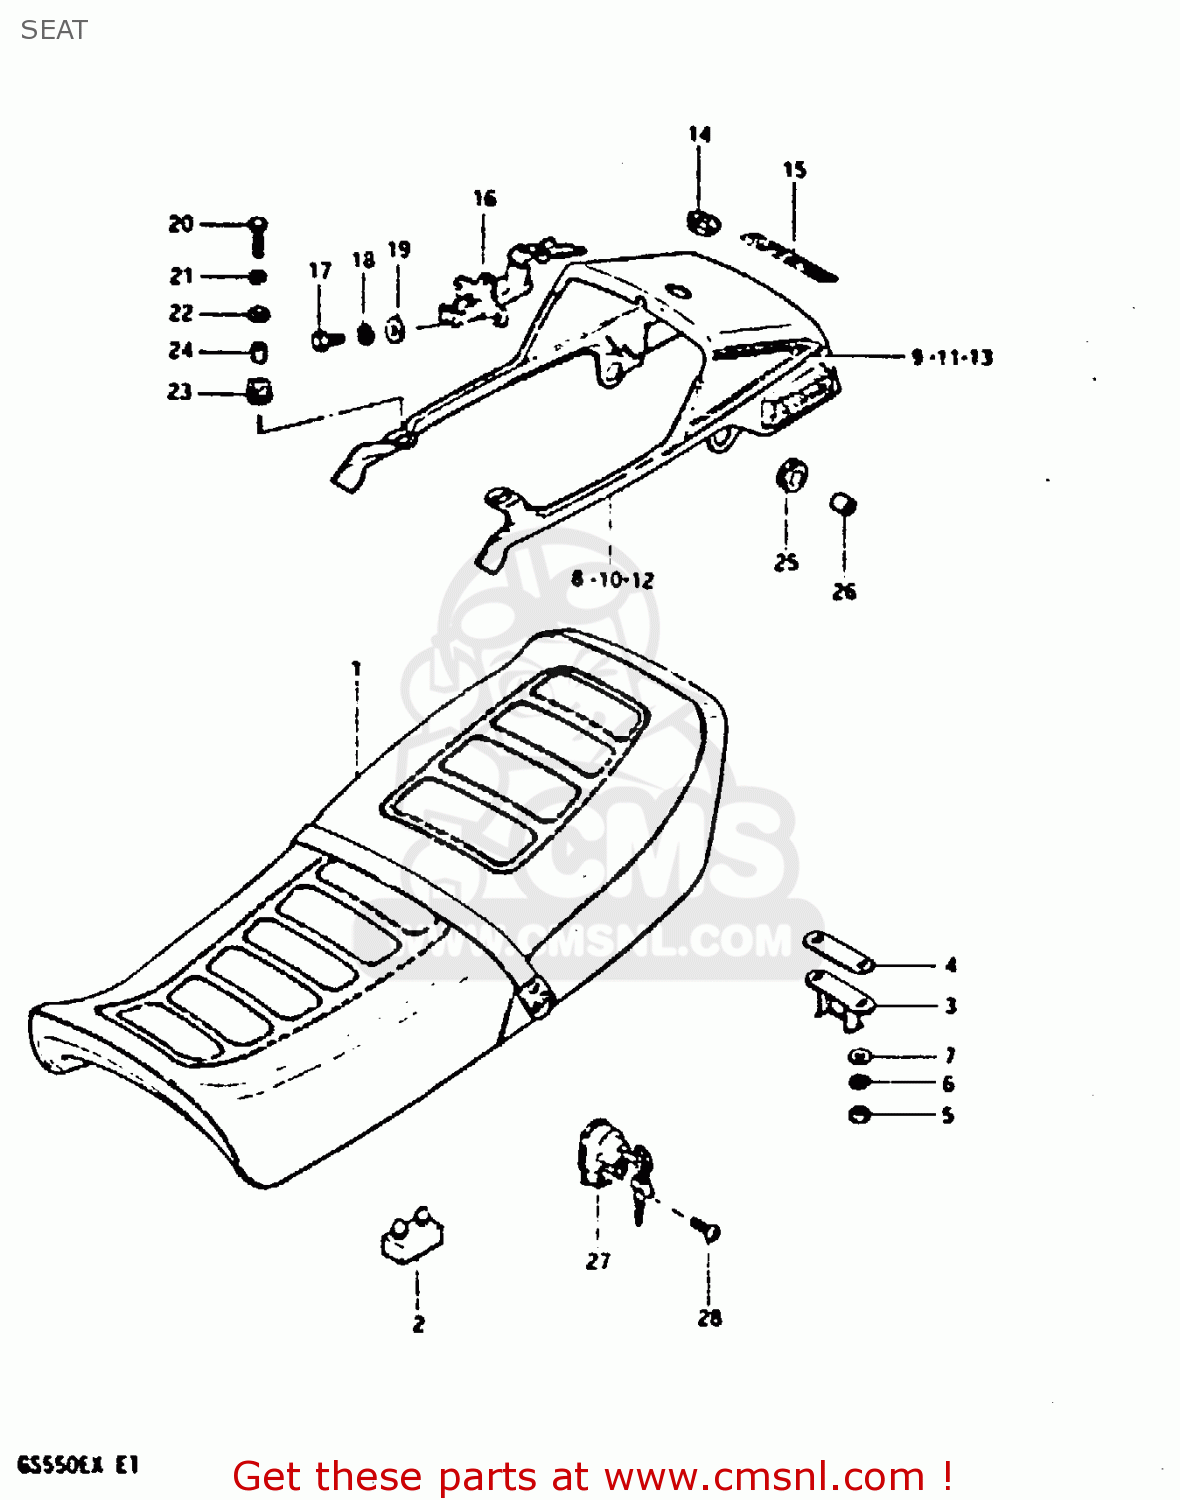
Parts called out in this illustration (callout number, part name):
1	SEAT ASSEMBLY
2	CUSHION
3	STRIKER,SEAT LOCK
4	SHIM,SEAT LOCK STRIKER
5	NUT 6MM
6	LOCK WASHER
7	WASHER
8	COVER, SEAT TAIL (BLACK)
9	TAPE SET
10	COVER, SEAT TAIL (RED)
11	TAPE SET
12	COVER, SEAT TAIL (BLUE)
13	TAPE SET
14	GROMMET,SEAT LOCK HOLE
15	EMBLEM,SEAT TAIL COVER
16	LOCK SET,SEAT
17	BOLT
18	LOCK WASHER
19	WASHER
20	BOLT
21	LOCK WASHER
22	WASHER(6,5X22X1.6)
23	CUSHION
24	SPACER(6.5X10.5X12)
25	CUSHION
26	SPACER
27	LOCK ASSY,HELMET
28	BOLT 5X25
